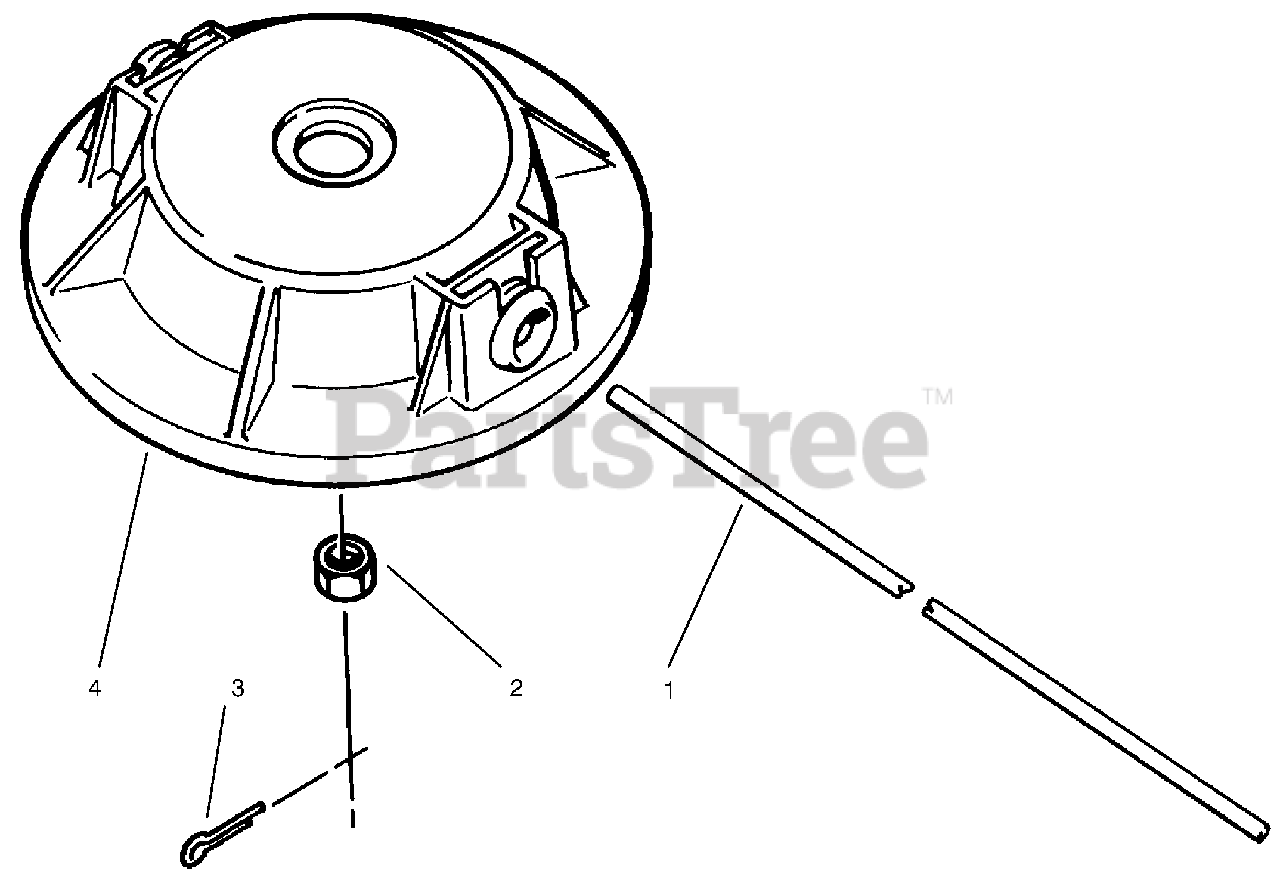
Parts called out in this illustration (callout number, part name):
1	Line-Cutting
2	Nut-L.H.
3	Pin-Cotter
4	Cutter Head Assembly
